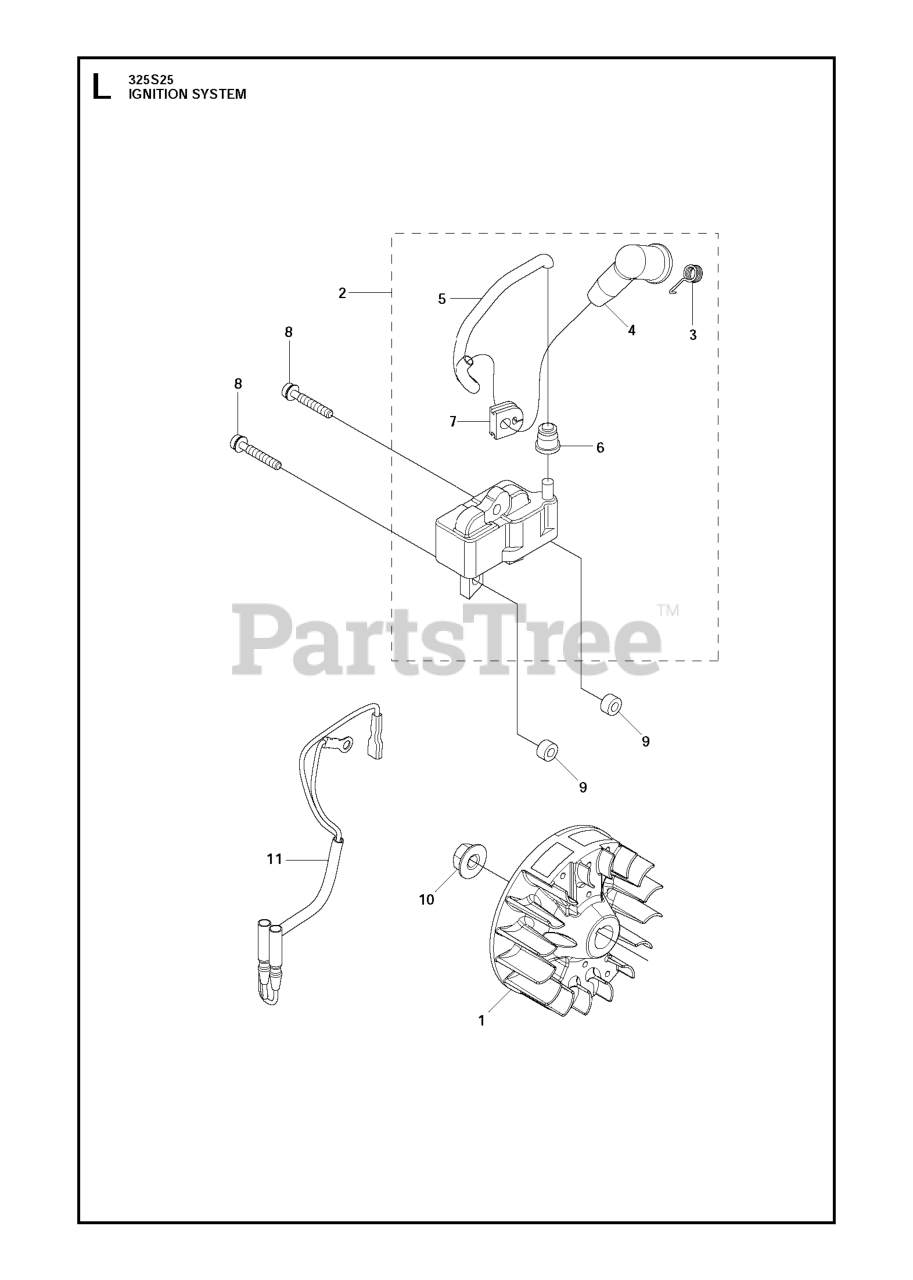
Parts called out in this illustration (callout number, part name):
6	CAP
7	GROMMET
9	SPACER
10	NUT
